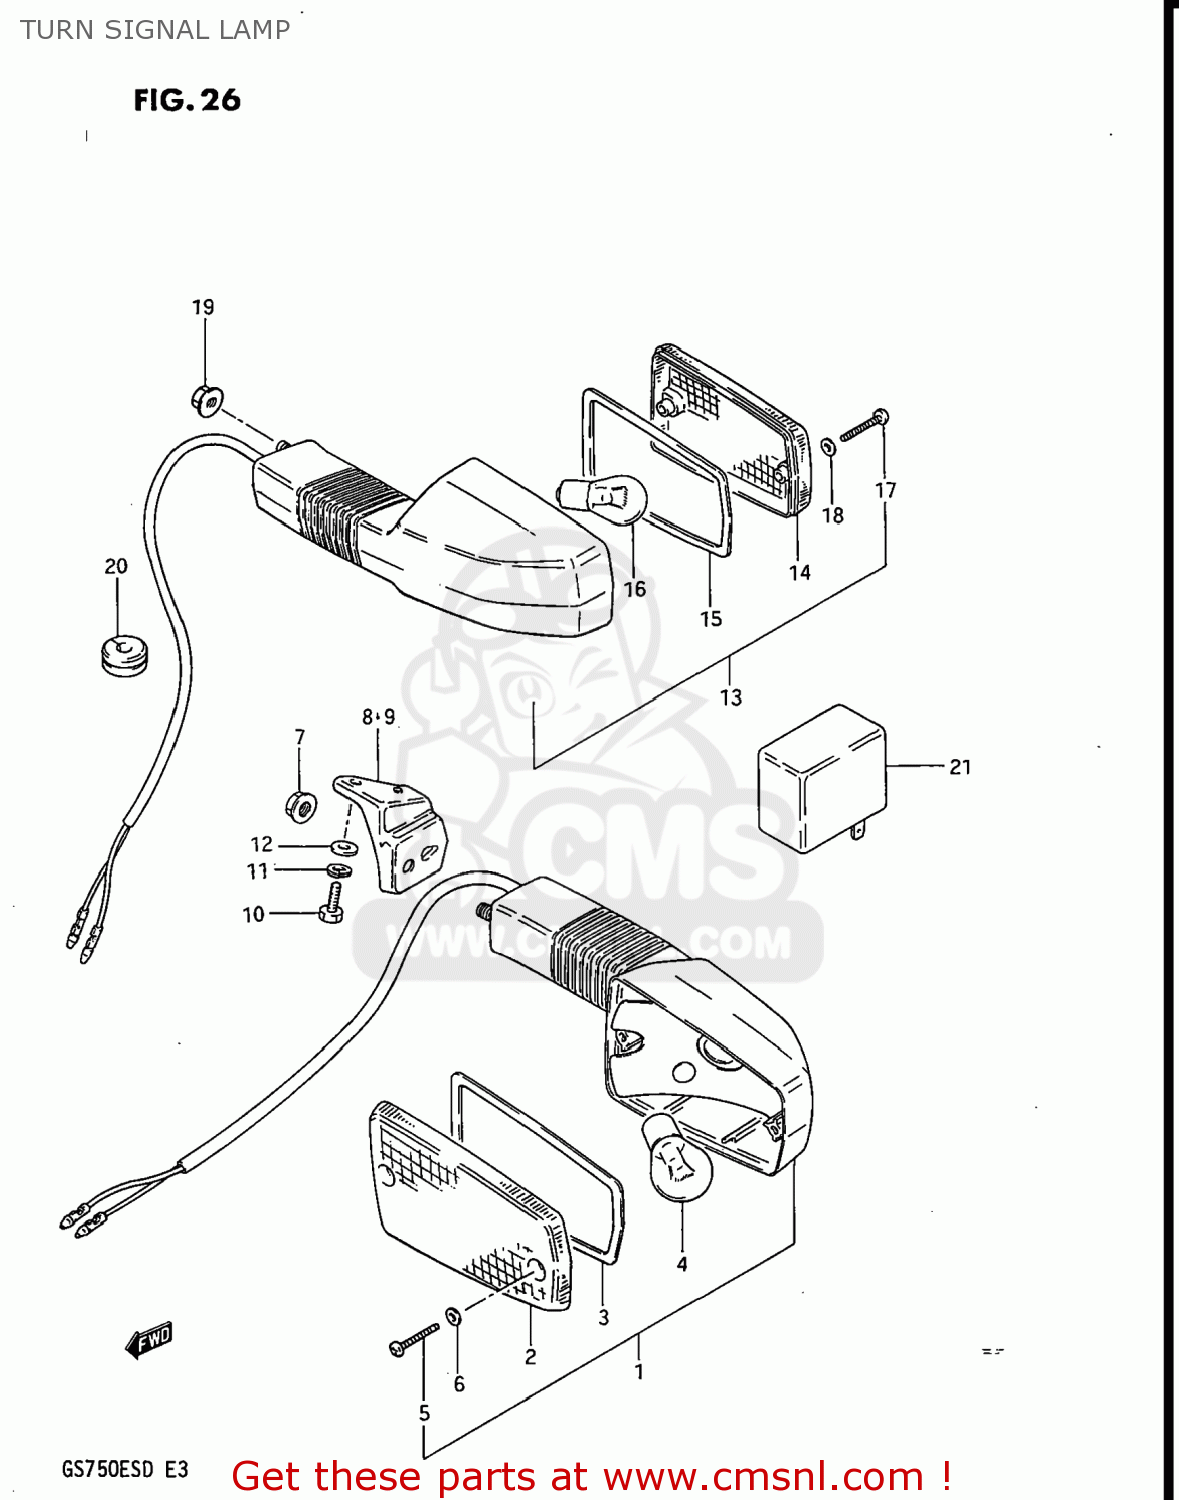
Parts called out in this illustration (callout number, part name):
1	LAMP ASSEMBLY,FRONT TURN SIGNAL
2	LENS
3	GASKET (NAS)
4	BULB(12V23W,STANLEY,A4577A)
5	SCREW
6	GASKET (NAS)
7	NUT
8	BRACKET,FRONT TURN SIGNAL
9	BRACKET,FRONT TURN SIGNAL
10	BOLT
11	LOCK WASHER
12	WASHER
13	LAMP ASSEMBLY,REAR TURN SIGNAL
14	LENS
15	GASKET (NAS)
16	BULB(12V23W,STANLEY,A4577A)
17	SCREW
18	GASKET (NAS)
19	NUT
20	GROMMET
21	RELAY,TURN SIGNAL
